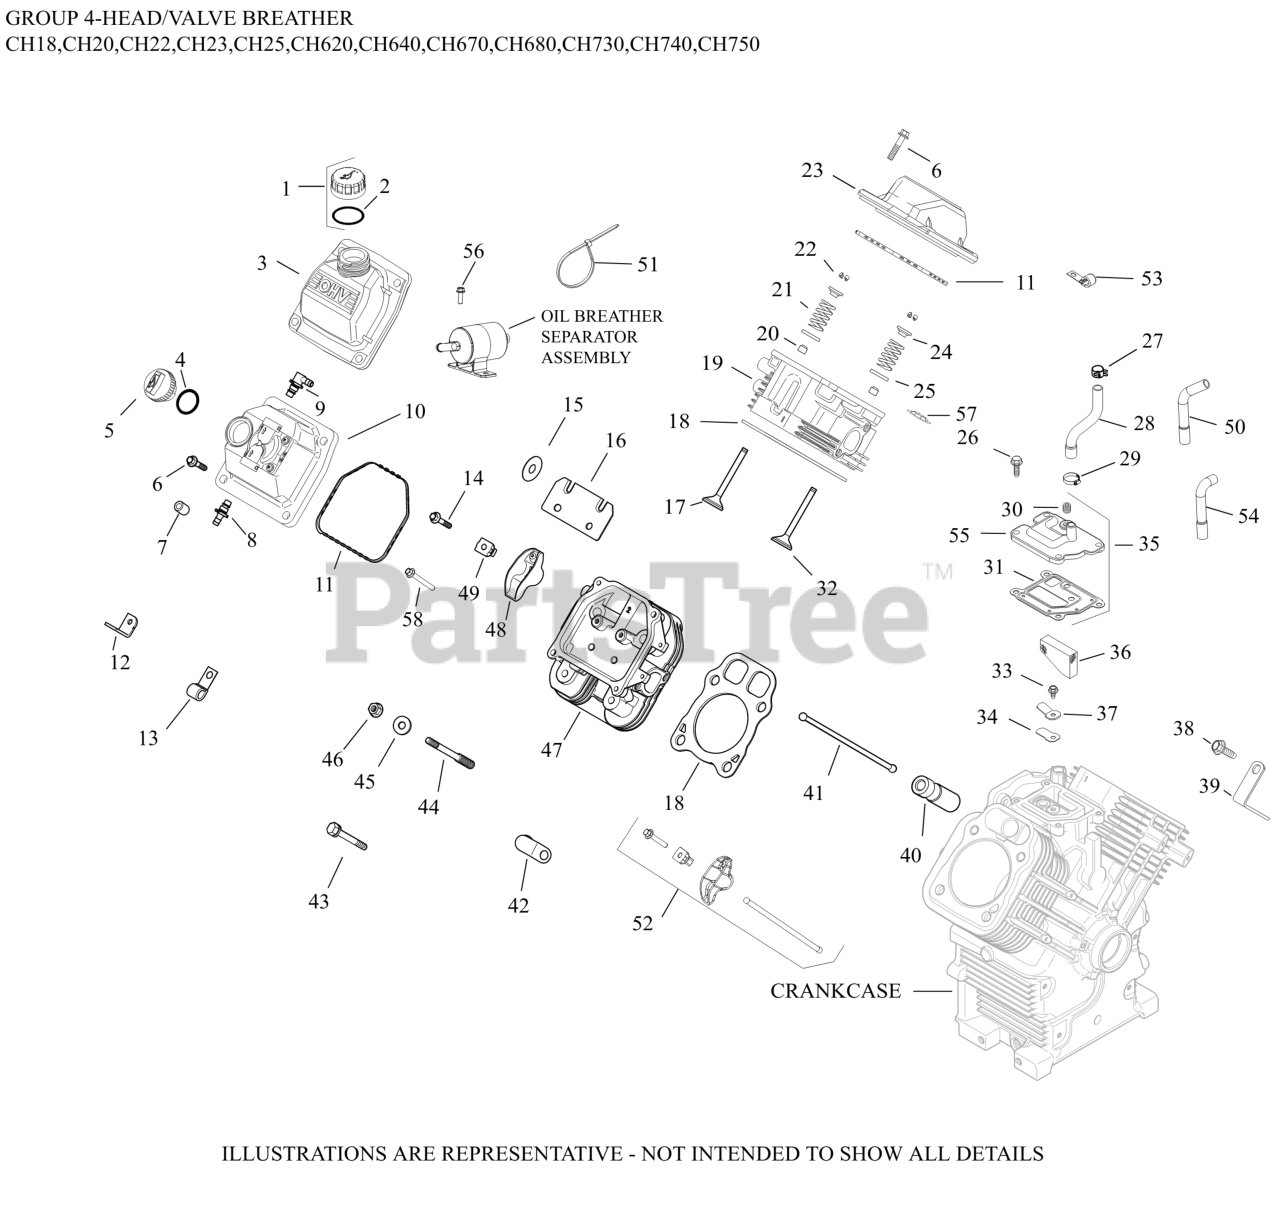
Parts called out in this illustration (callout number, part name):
1	KIT, OIL FILL CAP (BLACK)
2	O-RING, DIPSTICK
3	KIT, VALVE COVER-OIL FILL
6	SCREW, FLG M6X1.0X30
11	O-RING (YELLOW), VALVE CO
14	SCREW, FLG (BLACK) M6X1.0X34
15	WASHER, FLAT 6 MM
17	VALVE, EXHAUST
17	VALVE, EXHAUST (.25)
18	KIT, CYL HEAD GASKET (C17-22)
19	HEAD, ASSY CYLINDER (#1)-(#24318202S)
20	SEAL, VALVE BAND
21	SPRING, VALVE
22	KIT, RETAINER
23	KIT, VALVE COVER-PLAIN (PLASTIC)
24	CAP, VALVE SPRING
25	RETAINER, SPRING
27	SPRING CLAMP, HOSE
28	KIT, BREATHER HOSE AND CLAMP
31	GASKET, BREATHER
32	VALVE, INTAKE (STD)
32	VALVE, INTAKE (.25)
33	SCREW, FLG THD FRM M5X.8X10
34	REED, BREATHER-(#2440206S)
34	REED, BREATHER
36	FILTER, BREATHER
37	RETAINER, REED
38	SCREW, THREAD FORMING
39	STRAP, LIFT
40	LIFTER, VALVE HYDRAULIC-USE 25 351 11-S
41	ROD, PUSH
43	SCREW, FLG M10X1.5X90
47	HEAD, ASSY CYLINDER (#2)-(#24318203S)
48	ARM, ROCKER
49	PIVOT, ROCKER ARM
52	KIT, VALVE TRAIN
55	COVER, BREATHER
57	RETAINER, VALVE GUIDE (KM)
